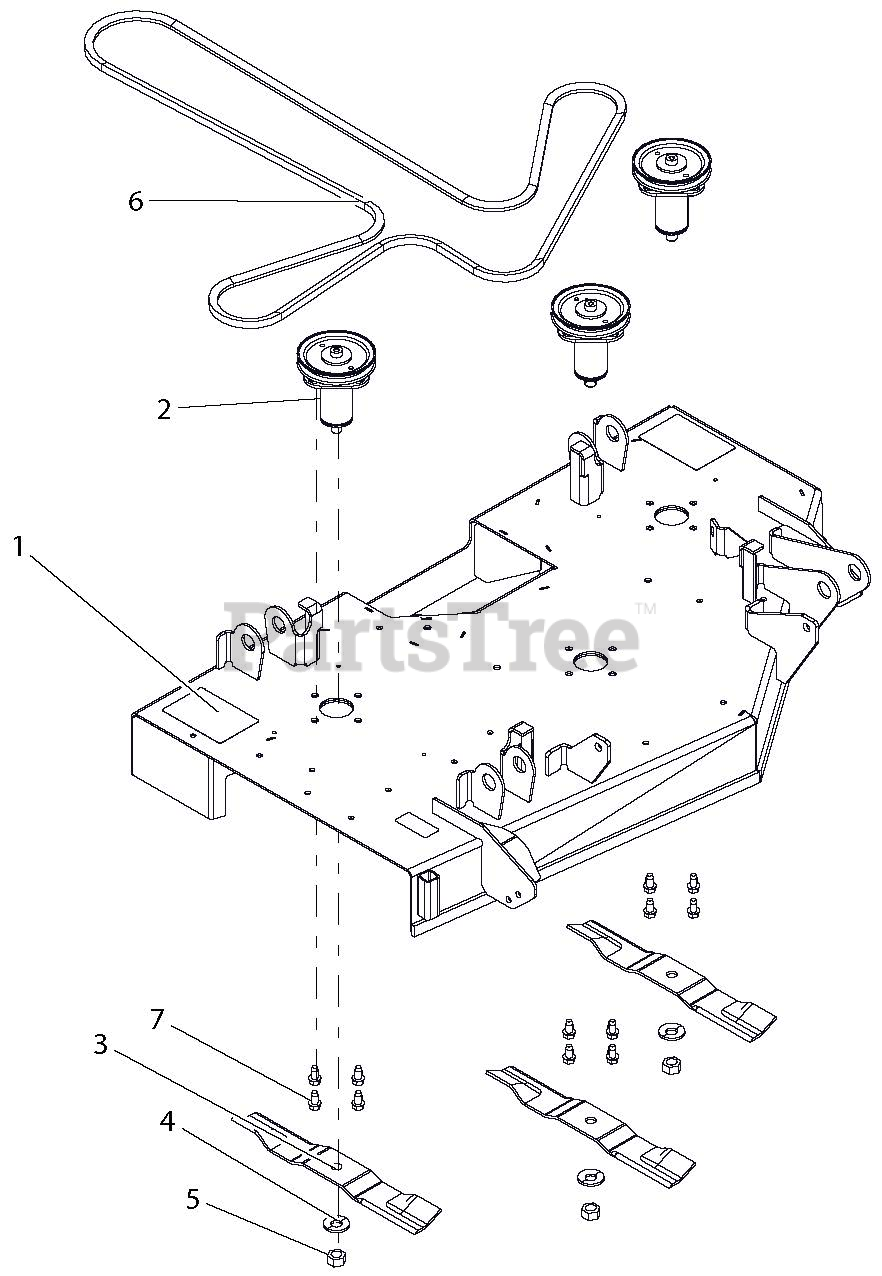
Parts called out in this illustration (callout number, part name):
1	KIT, 42" ARIENS DECK W/DECALS
2	KIT, DECK SPINDLE ASM-IKON-ZTX
3	BLADE, MOWER 15.00"
4	WSHR-BLVL .669X1.535X.138
5	NUT-HEX .62-18 YWZC
6	V-BELT, 4L-WRAPPED
7	@SCR-TAP .38-16X.75 HWH TR YWZ
